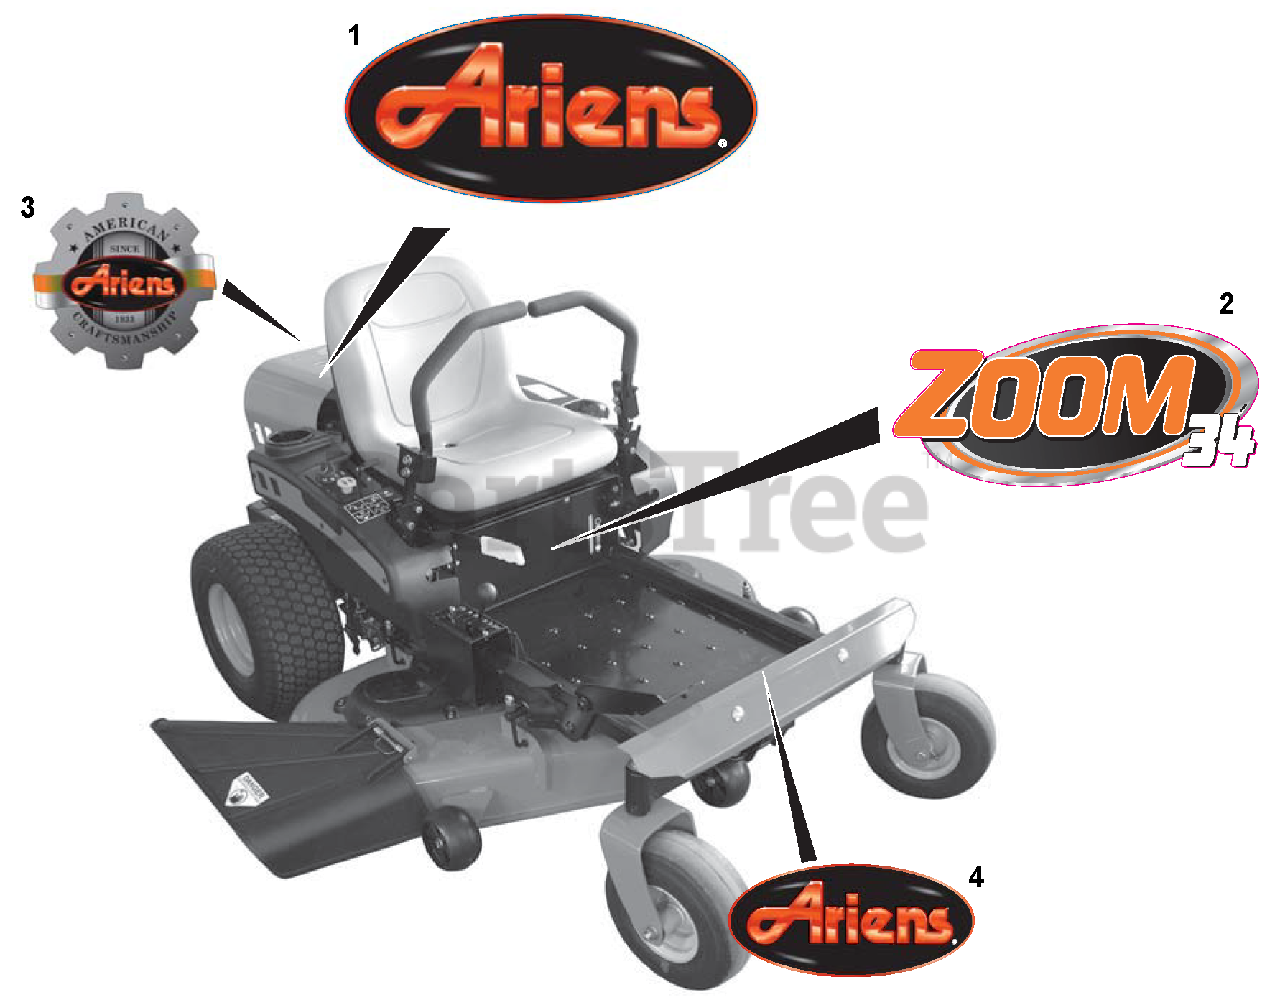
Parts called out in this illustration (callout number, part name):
1	DECAL, ARIENS JEWEL
2	DECAL, ZOOM 34
3	Decal, Ariens Heritage, Large
4	DECAL, ARIENS JEWEL
